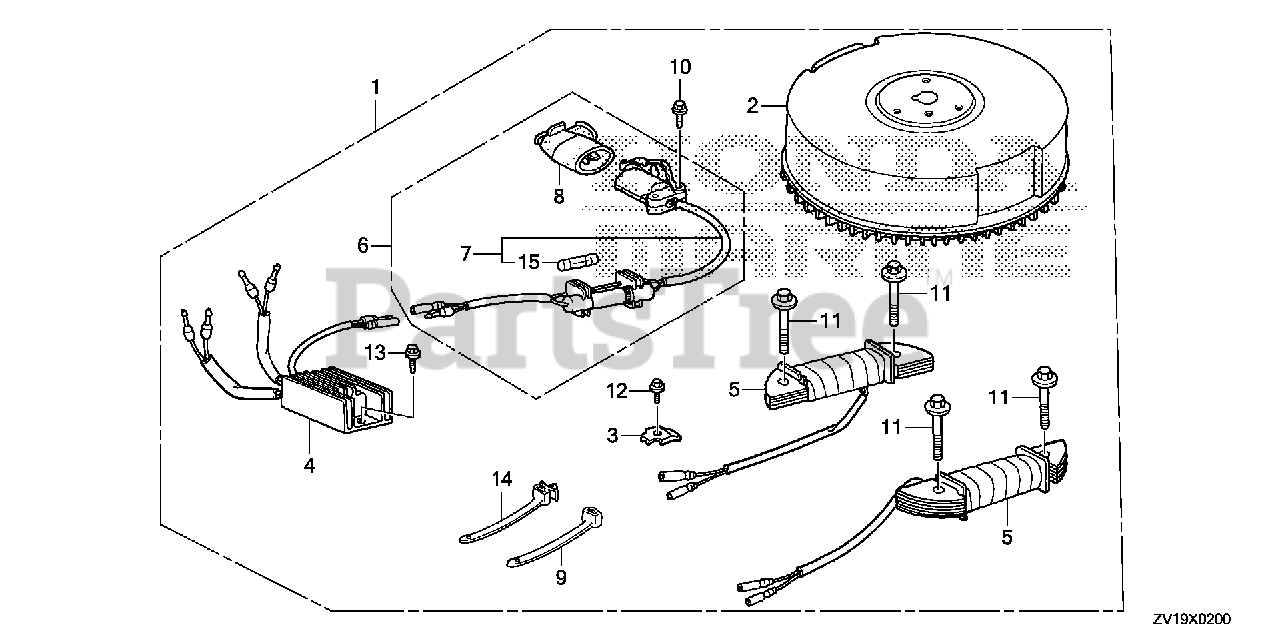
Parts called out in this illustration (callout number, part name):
1	RECEPTACLE KIT, CHARGE *TBLACK* (BLACK)
2	FLYWHEEL *TBLACK* (CHARGE) (BLACK)
3	CLAMP, WIRE
4	RECTIFIER ASSY., REGULATOR
5	COIL ASSY., CHARGE (12V-1.5A)
6	RECEPTACLE ASSY., CHARGE Use from Engine SN 1308875.
7	RECEPTACLE
8	PLUG, RECEPTACLE
9	TIE, CABLE (NATURAL 2.4X92) Use up to Frame SN 1300359.
10	BOLT, FLANGE (5X22)
11	BOLT, FLANGE (6X28) (CT200)
12	BOLT, FLANGE (5X10)
13	BOLT, FLANGE (6X16)
14	BAND, CABLE
15	FUSE A (5A)
